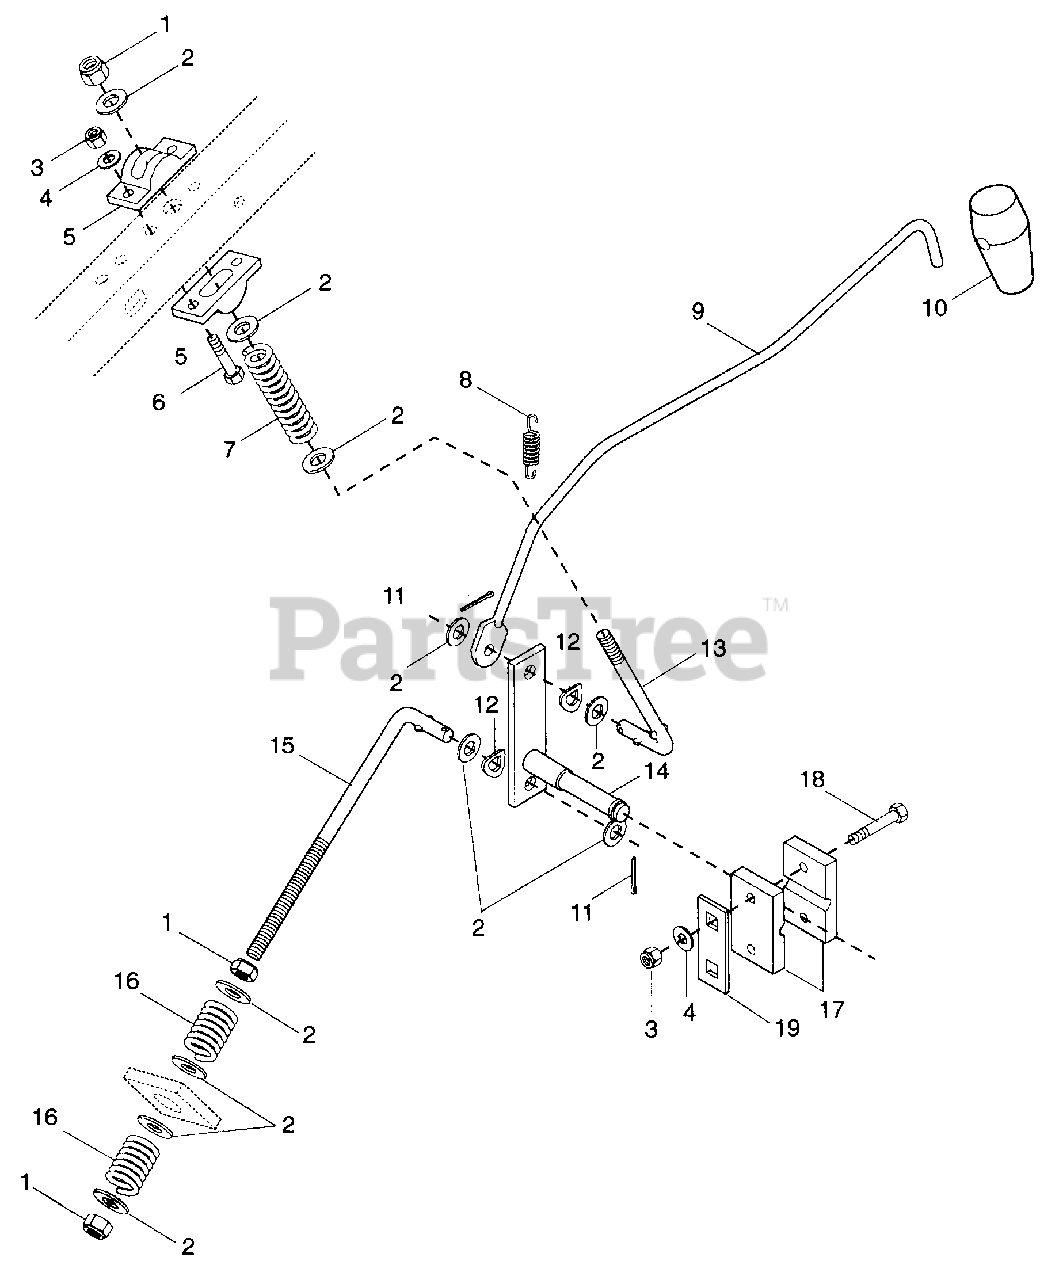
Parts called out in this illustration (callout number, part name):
1	Nut-Locking-Nylon .375-16
2	Washer-Flat-Steel .406 x .812 x .065
3	Nut-Locking-Nylon .250-20
4	Washer-Flat-Steel .281 x .62 x .065
5	Cam, Shifter
6	Bolt-Hex .25-20 x 1.00 Grade 5
7	Spring-Compression .081 x .720 x 2.75
8	Spring-Tension .041 x 1.25 x.50
9	Rod, Shifter
10	Handle, Rubber Shifter
11	Pin-Cotter .12 x .75
12	Spring Washer
13	Link, Shifter Stop
14	Weldment, Shifter Crank
15	Link, Shifter
16	Spring-Compression .125 x .78 x 1.00
17	Block, Shift Lever
18	Bolt-Hex .25-20 x 1.50 Grade 5
19	Shim, Mower Height Adjuster Bracket
